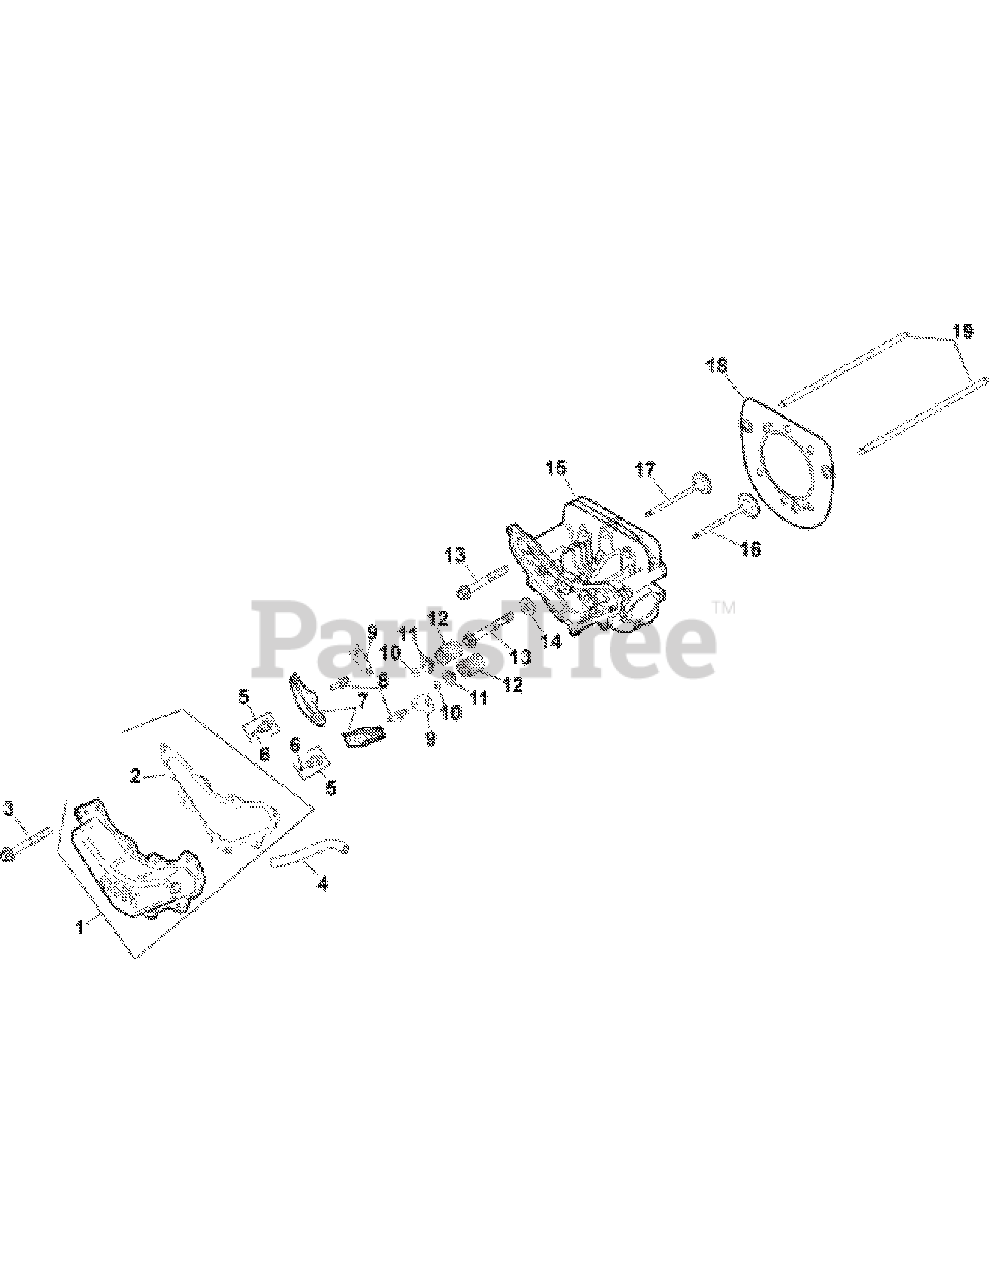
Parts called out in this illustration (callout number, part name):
1	KIT, VALVE COVER
2	GASKET, VALVE COVER
3	SCREW, FLG THD FRM M6X1.0X20
4	HOSE, BREATHER
5	KIT, ROCKER ARM PIVOT- DISCONTINUED
7	ARM, ROCKER
9	PLATE, PUSH ROD GUIDE
11	CAP, VALVE SPRING
12	SPRING, VALVE
13	SCREW, FLG M10X1.5X80
14	WASHER, FLAT 13/32"
15	HEAD, CYLINDER ASSEMBLY
18	KIT, CYLINDER HEAD GASKET
19	ROD, PUSH
